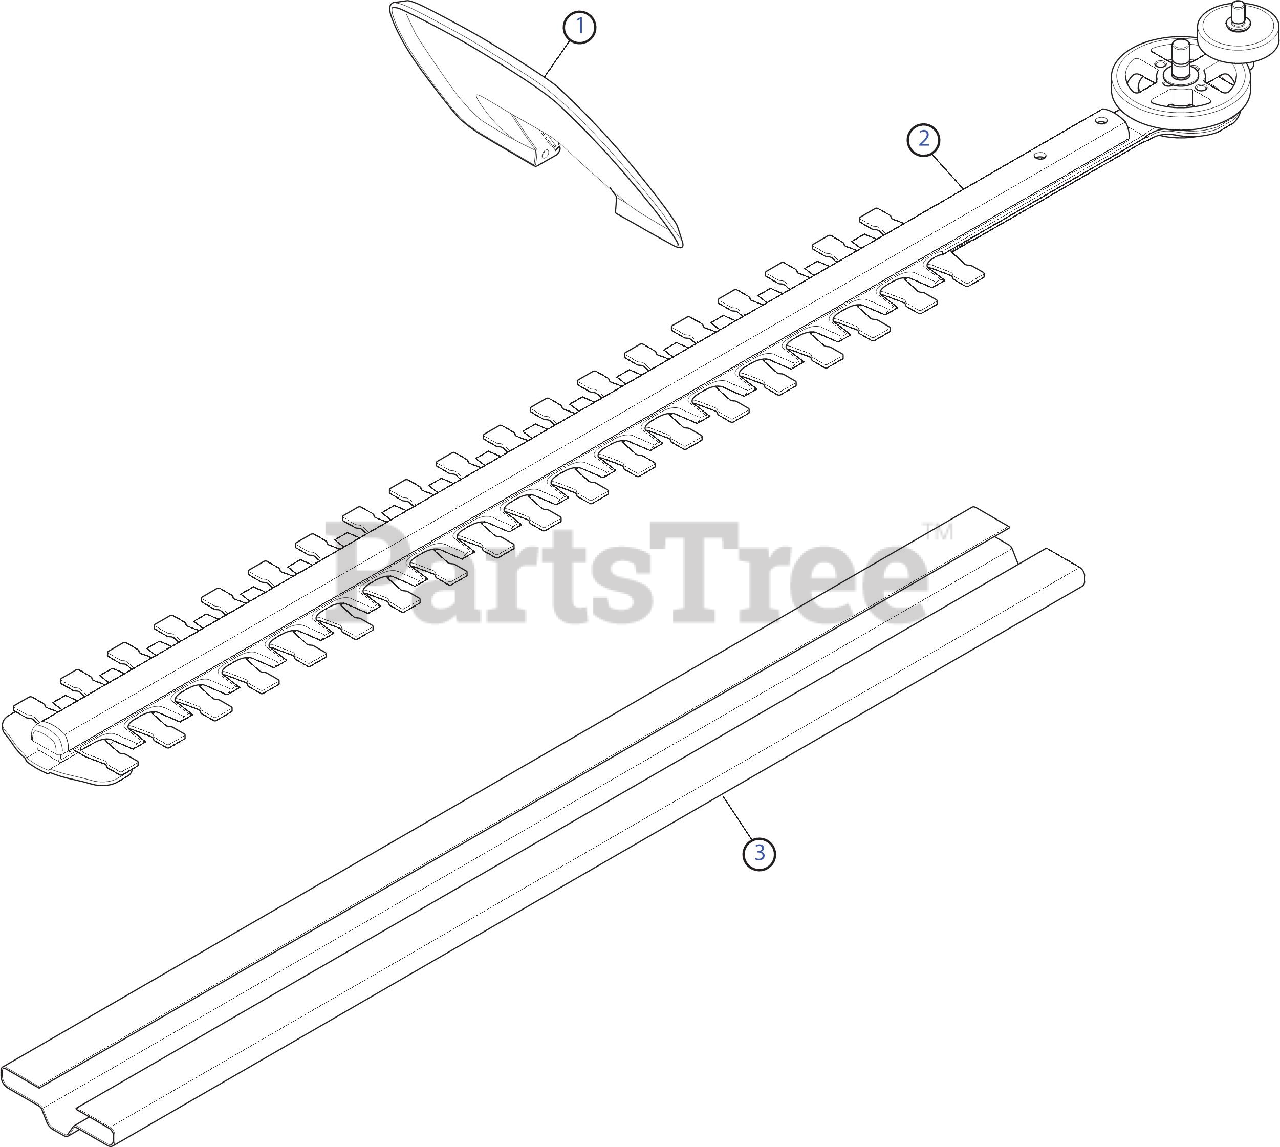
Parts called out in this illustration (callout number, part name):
1	Front Hand Guard
2	Blade Assembly
3	Scabbard
